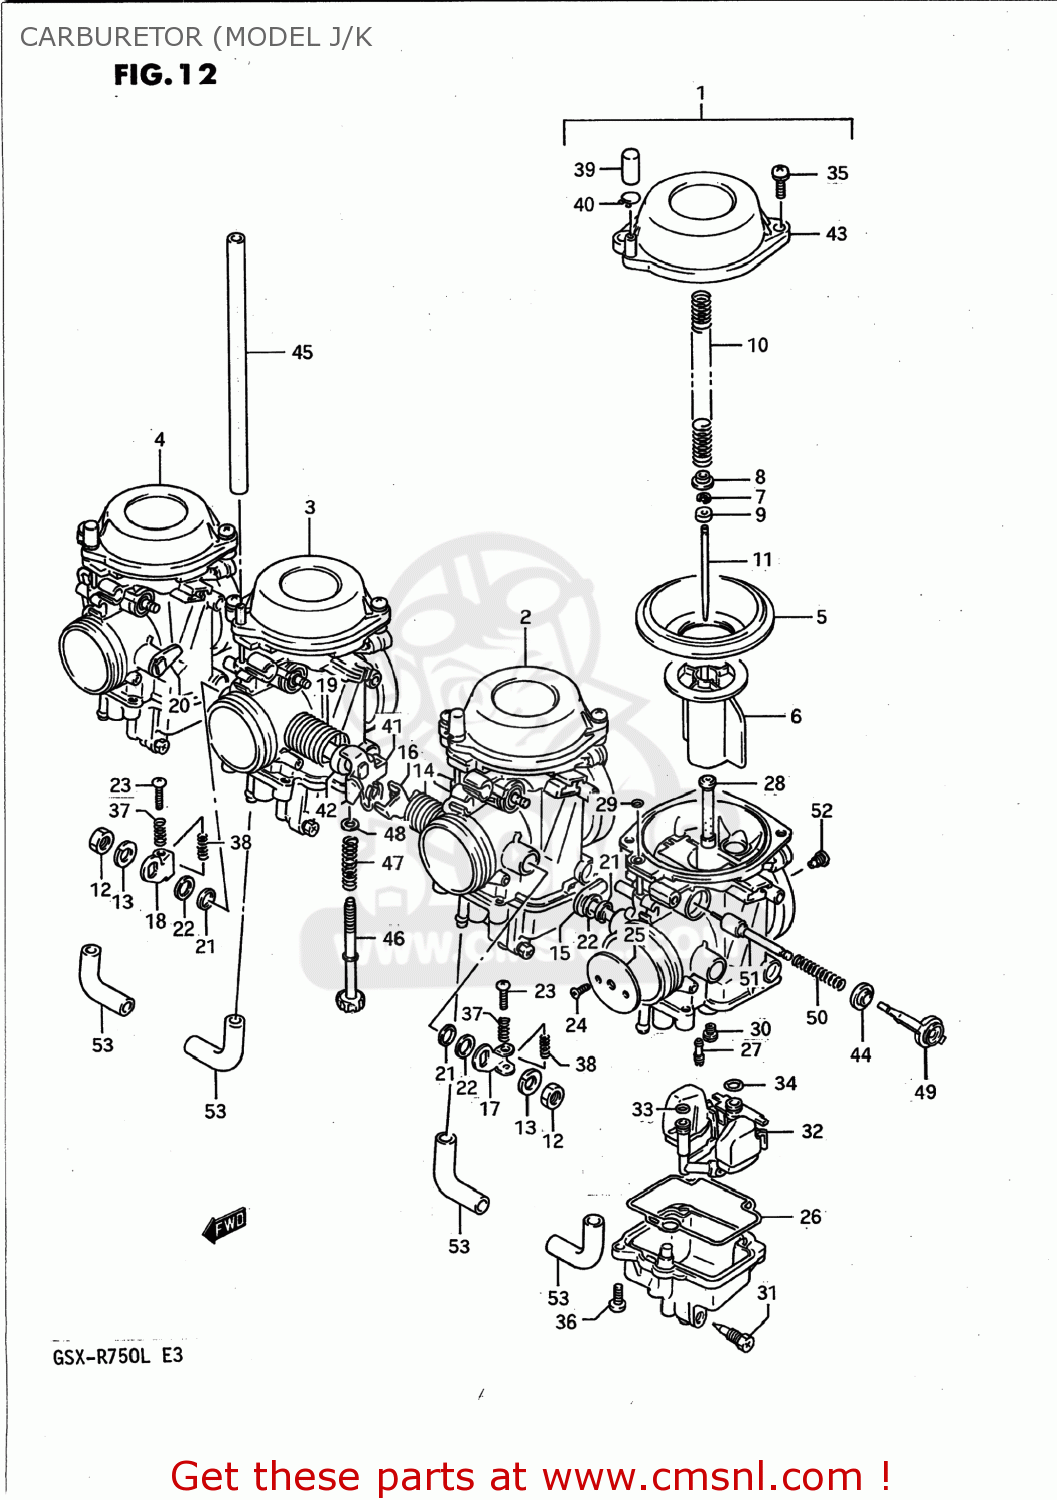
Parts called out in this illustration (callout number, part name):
1	CARBURETOR ASSEMBLY,LEFT
2	CARBURETOR ASSEMBLY,MIDDLE,LEFT
3	CARBURETOR ASSEMBLY
4	CARBURETOR ASSEMBLY
5	DIAPHRAGM
6	VALVE,PISTON
7	CLIP,NEEDLE
8	RING
9	RING
10	SPRING
11	NEEDLE,JET
12	NUT
13	WASHER,LOCK,8.
14	SPRING
15	SHAFT ASSEMBLY
16	SHAFT ASSEMBLY
17	LEVER
18	LEVER
19	SPRING
20	SHAFT ASSEMBLY
21	SEAL
22	GASKET,THROTTLE SHAFT (NAS)
23	ADJUSTER
24	SCREW
25	VALVE,THROTTLE
26	GASKET,FLOAT CHAMBER (MCA)
27	JET,PILOT(32.5)
28	JET,NEEDLE(Y-5)
29	O RING
30	JET,MAIN(112.5)
31	SCREW
32	FLOAT/NEEDLE VALVE ASSY
33	O RING
34	O-RING,NEEDLE VALVE
35	SCREW
36	SCREW
37	SPRING
38	SPRING
39	CAP
40	CLIP
41	SHAFT ASSEMBLY
42	RING
43	COVER,DIAPHRAGM
44	CAP,STARTER
45	HOSE
46	SCREW
47	SPRING
48	WASHER
49	HOLDER,GUIDE
50	SPRING
51	PLUNGER ASSY
52	JET,AIR
53	HOSE
